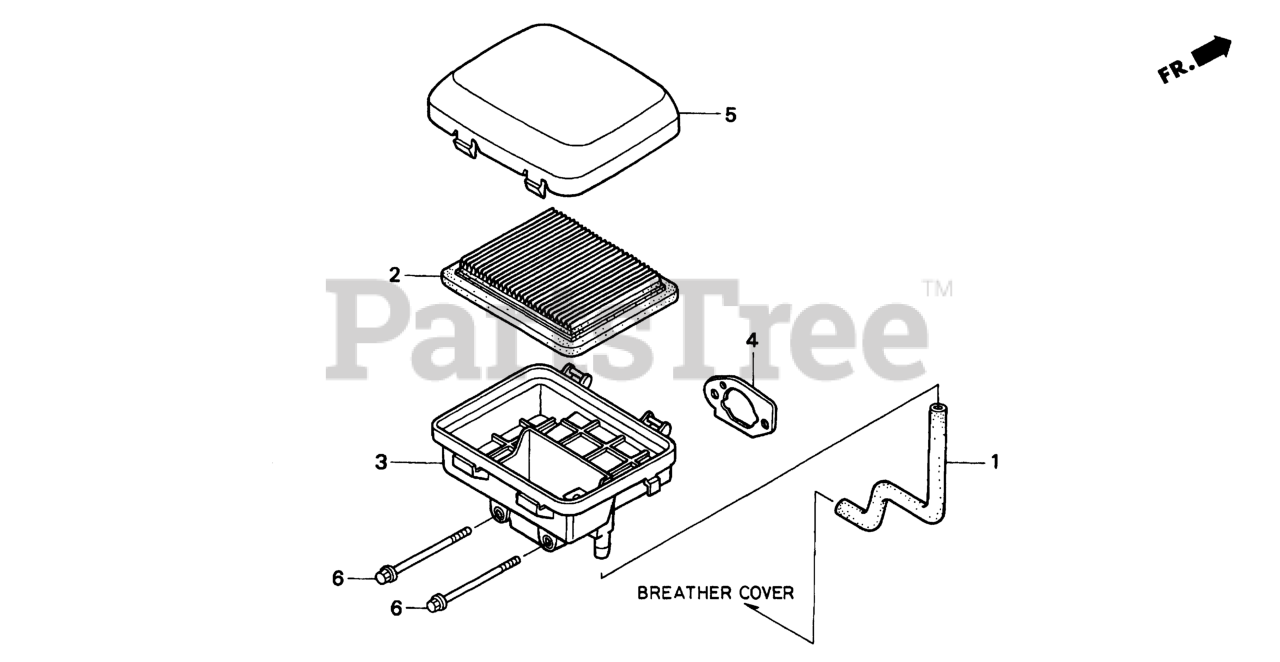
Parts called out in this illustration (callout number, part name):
1	TUBE, BREATHER
2	ELEMENT, AIR CLEANER (ENGINE NO.)
2	ELEMENT, AIR CLEANER (TOYO ROKI) (ENGINE NO.)
3	HOUSING, AIR CLEANER
4	GASKET, AIR CLEANER
5	COVER, AIR CLEANER
6	BOLT, FLANGE (6X112) (CT200)
